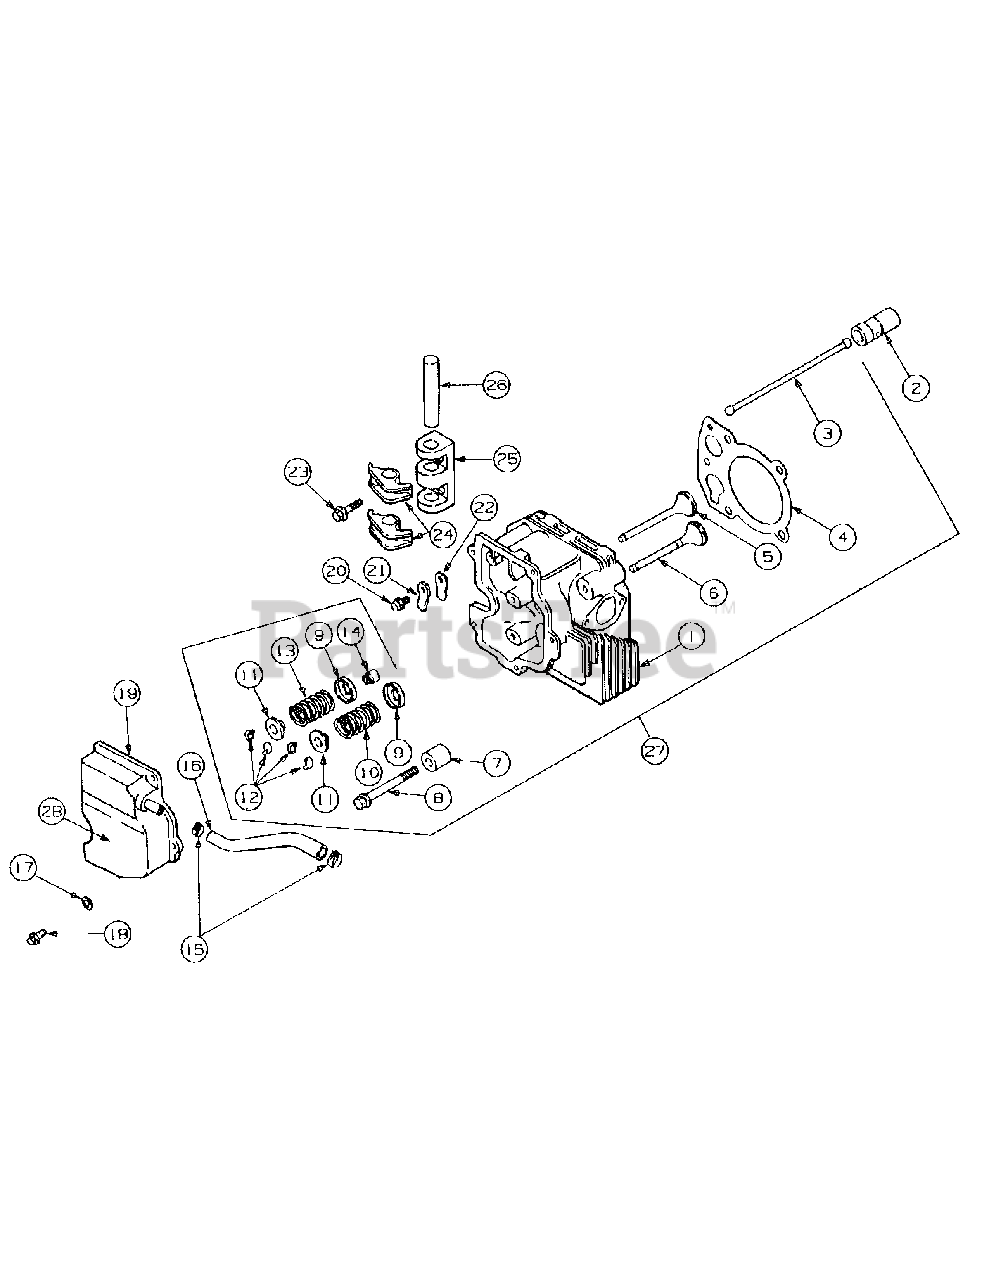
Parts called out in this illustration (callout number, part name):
1	Cylinder Heaf
2	Lift, Valve
3	Rod, Push
4	Gasket,Cylinder
5	Valve, Intake(std)
5	Valve, Intake(.25)
6	Valve, Exhaust(std)
6	Valve, Exhaust(.25)
7	Spacer, Head Bolt
8	Screw, Cyl. Head, M10 x 1.5 x 81
9	Retainer, SPring
10	Spring, Exhaust Valve
11	Cap, Valve Spring
12	Kit, REtainer
13	Spring, Intake Valve
14	Seal, Intake Stem
15	Clamp, Hose
16	Hose, Breather
18	Screw, Valve Cover,M6 x 1.0 x 20
19	Cover, Valve w/Nipple
20	Screw, Breather Reed Ret. M5 x 0.8 x 10
21	Retainer, Breather Reed
22	Reed, Breather
23	Screw, Rocker Bridge, M6 x 1.0 x 25
25	Bridge, Rocker Arm
26	Shaft, Rocker Arm
27	Kit, Cylinder Head
28	Graphic, OHV Engine
